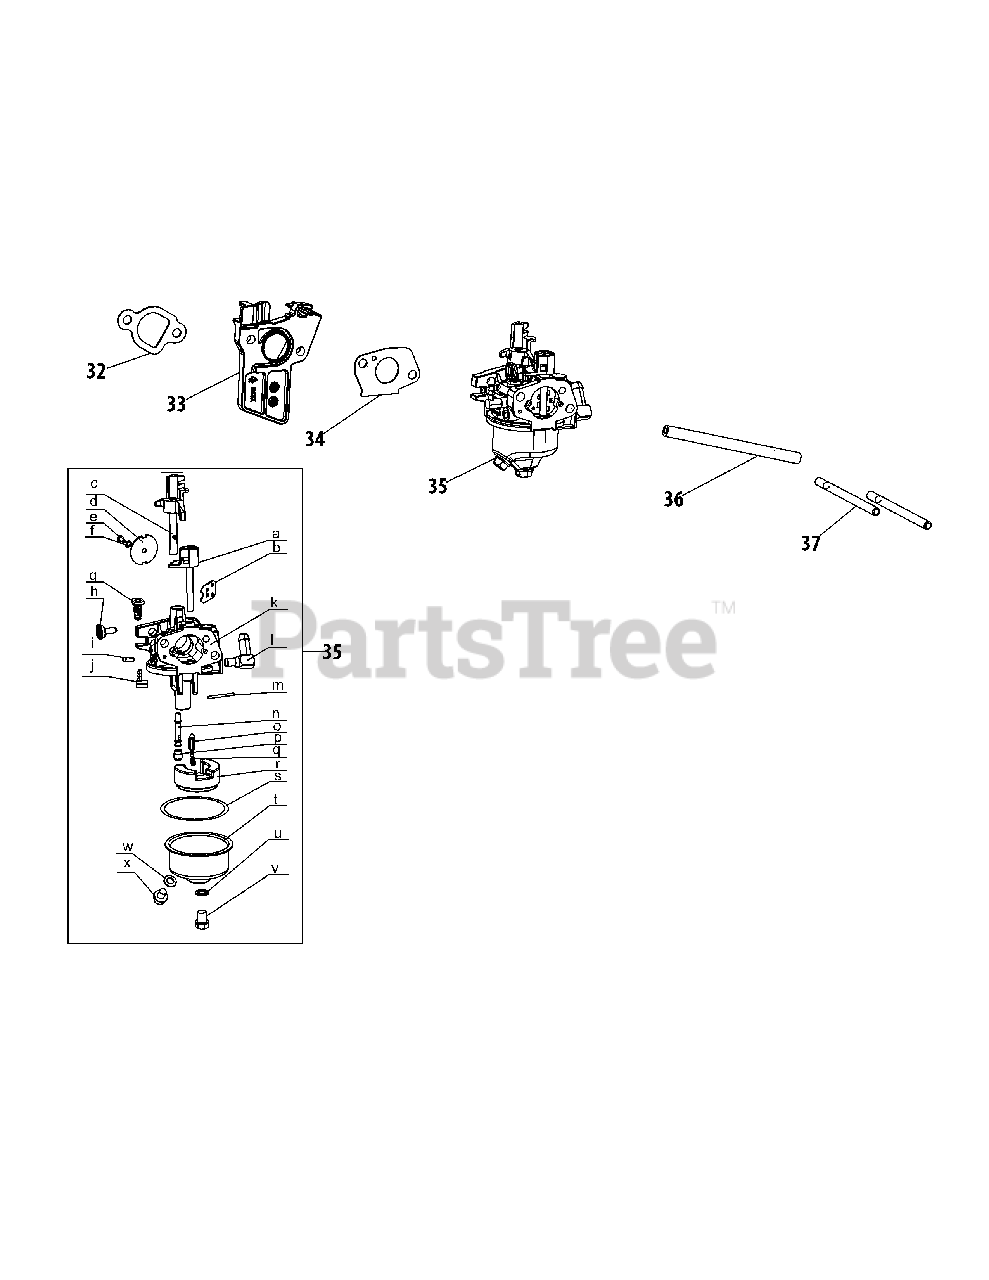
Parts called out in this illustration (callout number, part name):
32	Gasket, Carburetor Insulator
33	Insulator
34	Gasket, Carburetor
35	Carburetor
36	Fuel Hose,3.2×6.5×170
37	Stud, M6×92
